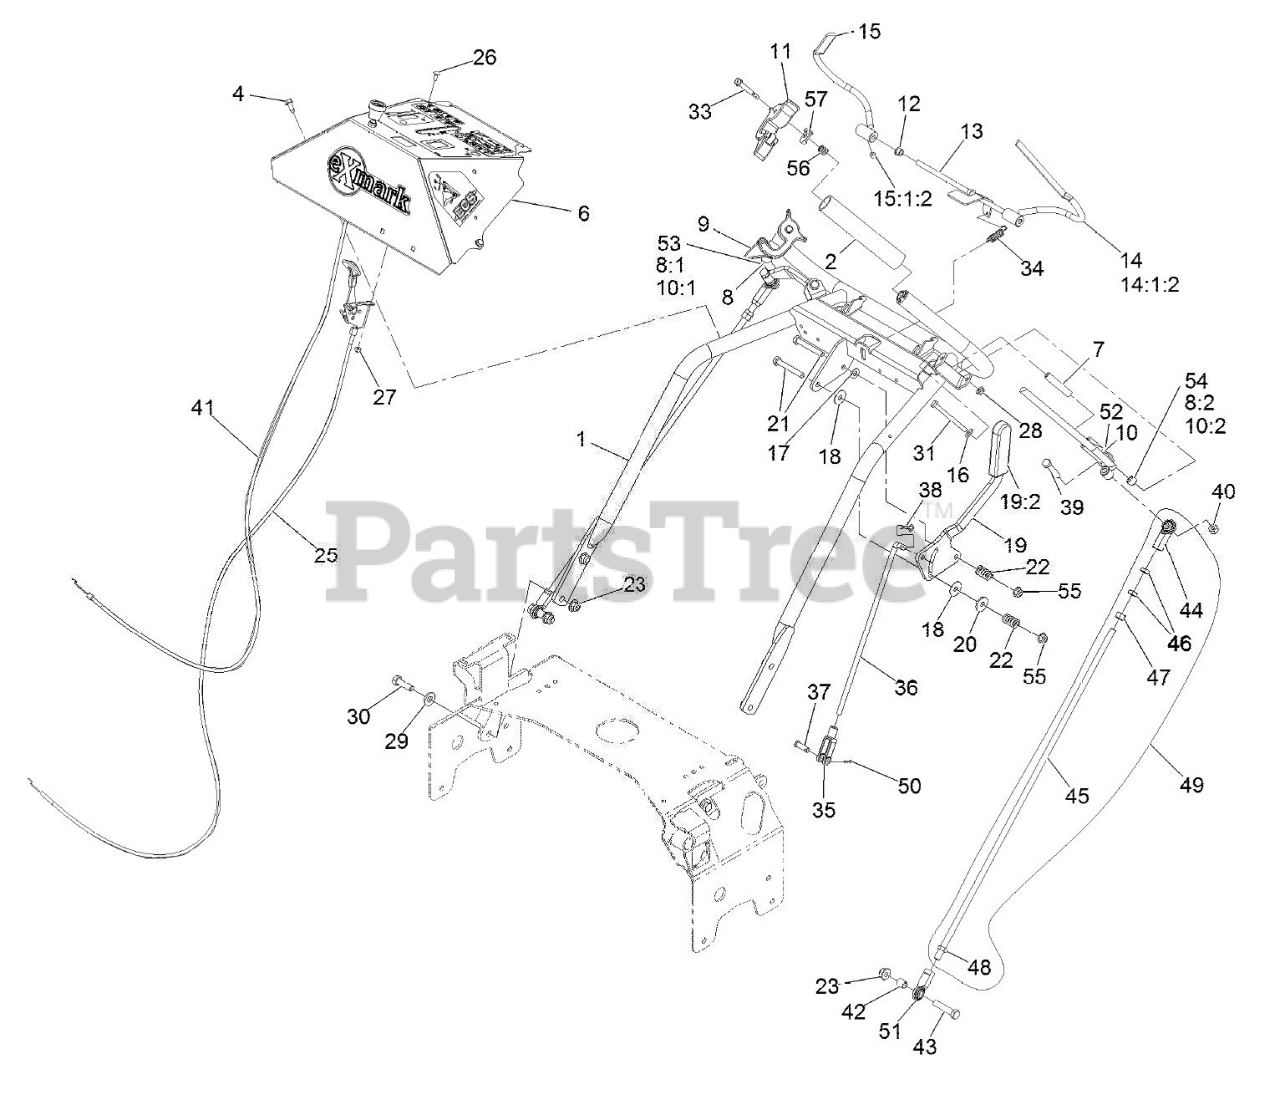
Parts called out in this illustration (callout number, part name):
1	WELD, HANDLE
2	GRIP-BAR, HANDLE
4	SCREW-HWH
6	ASM, CONSOLE W/ DECALS
7	BUSHING-LEVER, DRIVE
8	DRIVE LEVER-ASM, RH
8:1	WLD,RH DRIVE LEVER
8:2	BUSHING-SLEEVE
9	ASM,LATCH RH THUMB
10	DRIVE LEVER-ASM, LH
10:1	WLD,LH DRIVE LEVER
10:2	BUSHING-SLEEVE
11	ASM,LATCH LH THUMB
12	BUSHING-NYLON
13	WLD,OPC LEVER AXLE
14	WLD,LH OPC LEVER
14:1:2	SCREW-SET
15	WLD,RH OPC LEVER
15:1:2	SCREW-SET
16	WASHER-FLAT
17	WASHER-PLAIN
18	WASHER-FRICTION
19	LEVER, SHIFT W/GRIP
19:2	GRIP-HANDLE, STEERING
20	WASHER-FRICTION
21	SCREW-HH
22	SPRING-COMPRESSION
23	NUT-HF, NI
25	CONTROL-THROTTLE
26	BOLT-CARR
27	NUT-LOCK, NI
29	WASHER-BELLEVILLE
30	SCREW-HH
31	SCREW-HH
33	SCREW-SHOULDER
34	SPRING-EXTENSION
35	YOKE-ADJUSTABLE
36	ROD,SPEED CONTROL
37	PIN-CLEVIS
38	PIN-COTTER
39	SCREW-HH
40	NUT-LOCK, NI
41	CABLE, CHOKE
42	SPACER-TUBE, PUMP LINK
43	SCREW-HH
44	JOINT-BALL, END
45	LINK,DRIVE (PLTD)
46	NUT-HJ
47	NUT-HEX
48	NUT-HEX JAM, LH
49	DRIVE LINK ASM
50	PIN-COTTER
51	JOINT-BALL END, LH
52	WLD,LH DRIVE LEVER
53	WLD,RH DRIVE LEVER
54	BUSHING-SLEEVE
55	NUT-HF, NI
56	SPRING-TANK, FUEL
57	LATCH, ECS
